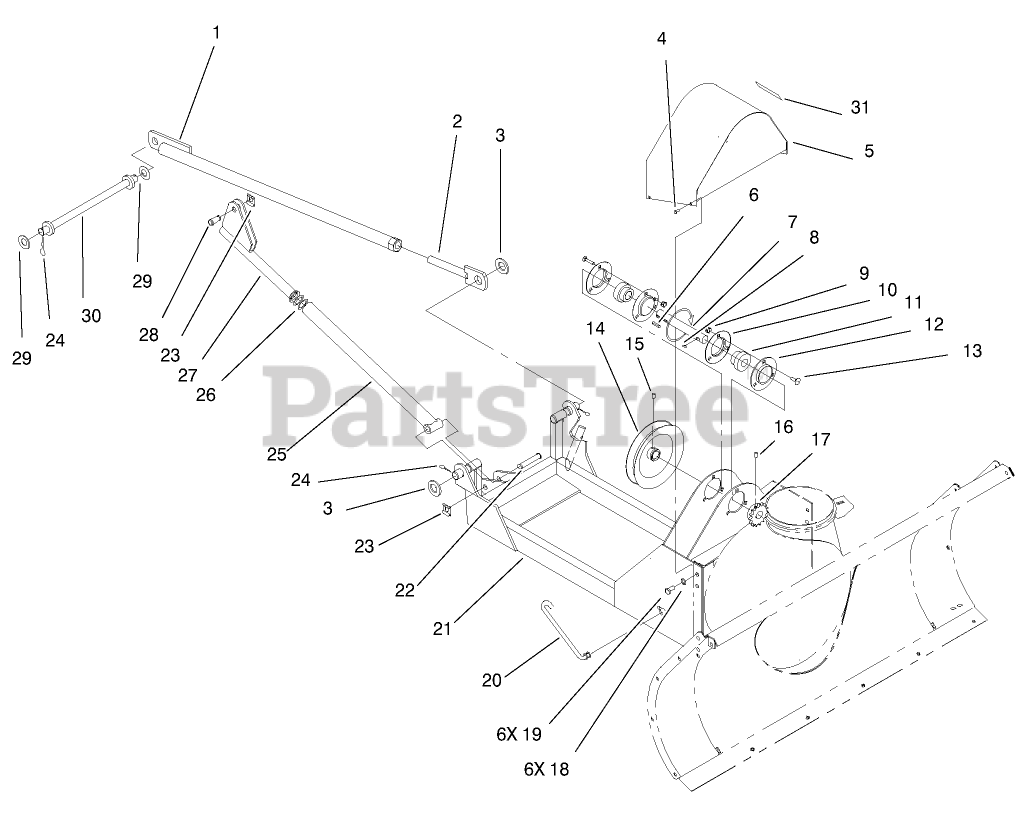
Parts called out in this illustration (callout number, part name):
2	ADJUSTER ASM
3	WASHER-FLAT
4	SCREW-TAPTITE
5	PULLEY COVER ASM
6	KEY
9	NUT-LOCK, NI
10	FLANGE-RELUBE
11	BEARING AND COLLAR
12	FLANGE
13	BOLT-CARR
14	PULLEY-DRIVE
15	SCREW-SQH
16	SCREW-SET
18	WASHER-LOCK
19	SCREW-HH
20	LINK-SPRING TENSION
21	FRAME ASM
22	PIN-CLEVIS
23	CLIP-PIN
24	PIN-COTTER, HAIR
25	ROD-LIFT
26	WASHER-FLAT
28	PIN-CLEVIS
29	WASHER-FLAT
30	LINK ASM
31	DECAL-IMPORTANT
